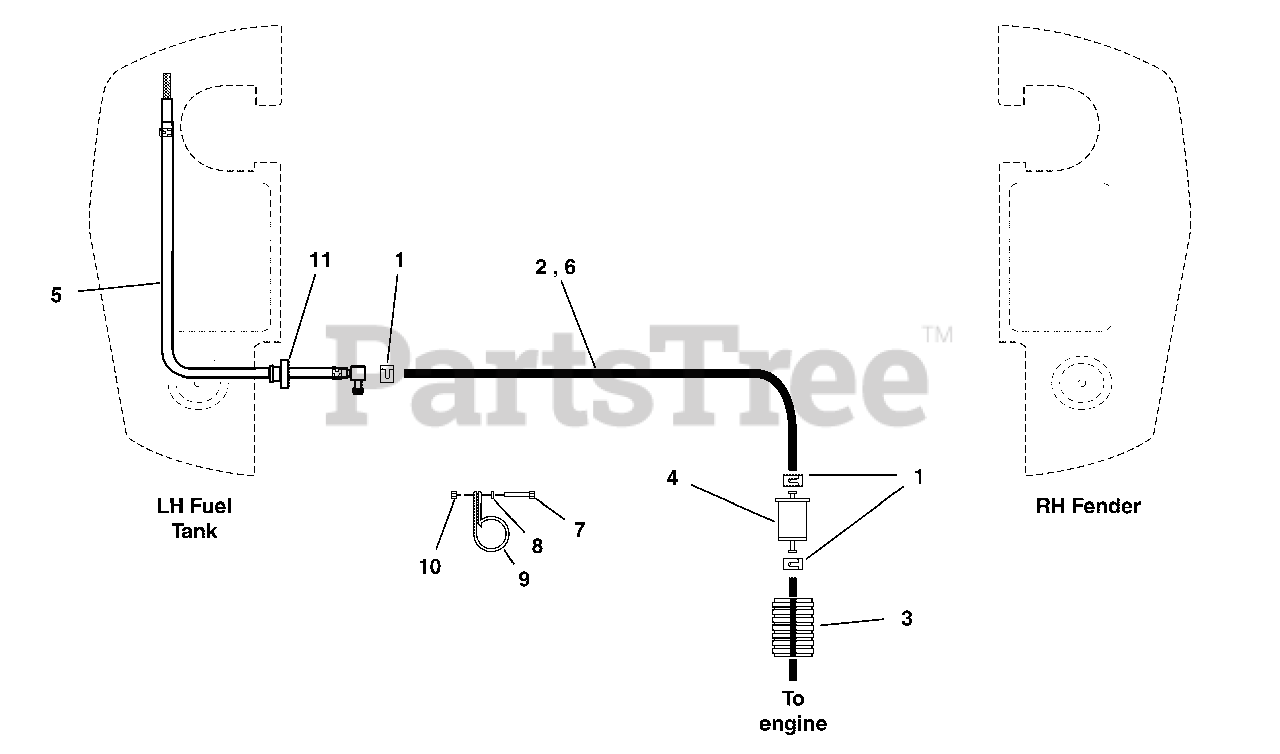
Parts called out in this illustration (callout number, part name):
1	CLAMP, HOSE, EXTERNAL, 1/2 - RED
2	HOSE, 1/4" FUEL, 29.00"
3	WIRE LOOM, 1/2 ID, 13.00 LONG
4	FUEL FILTER (SV)
5	HOSE ASSEMBLY
6	HOSE, 1/4" FUEL, 9.00"
7	CAPSCREW, Hex Head, 1/4-20 x 3/4 (stiffener to top of cover)
8	WASHER, 1/4, Flat, GR5 Zinc/Clear
9	CLAMP, VINYL INSULATED, 1.00
10	NUT, 1/4-20, GR5 Flanged Nylock, Zinc/Clear
11	BUSHING-FUEL TANK RED RUBBER (SV)
